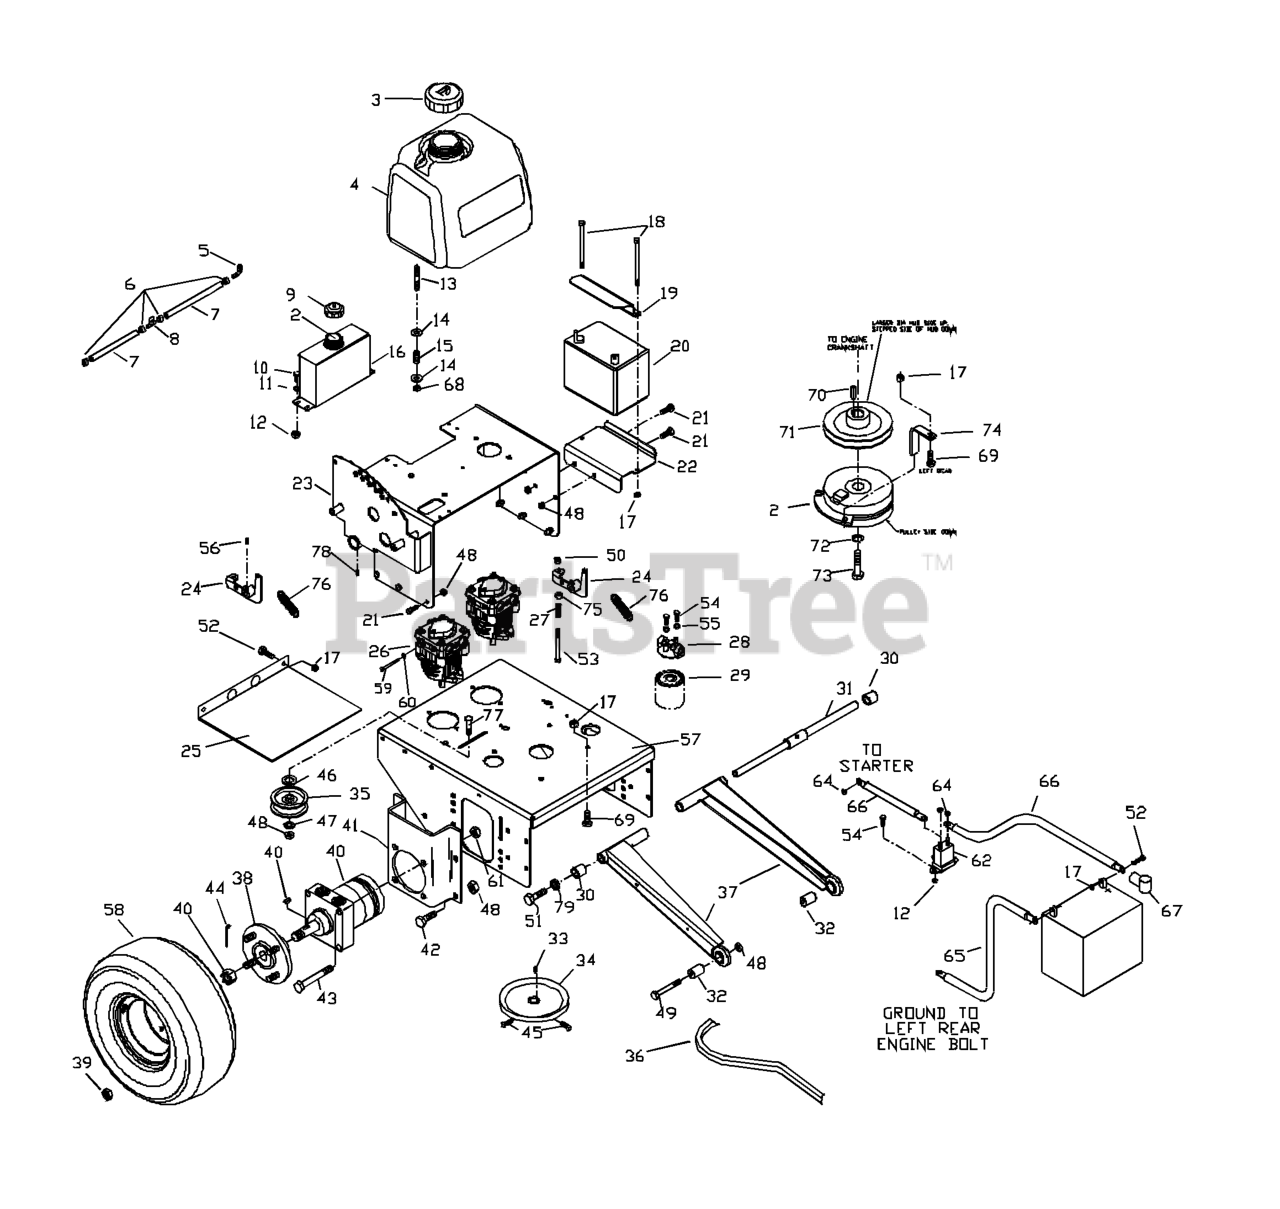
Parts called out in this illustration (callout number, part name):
1	CABLE, THROTTLE (17 KAW.)
3	FUEL CAP ANTI-SPLASH
5	HOSE BARB 90 DEGREE
6	HOSE CLAMP
7	GAS LINE 10"
8	FUEL VALVE
9	HYDRAULIC CAP
10	HCS 1/4C X 3/4 HCS
11	WASHER 1/4 FLAT
12	NUT 1/4C CENTER LOCK
13	STUD, 5/16C
14	WASHER 5/16 FLAT
16	OIL TANK BLK
17	NUT 5/16C CENTERLOCK
18	HEX SCREW 5/16 X 7.5
19	BATTERY STRAP
20	BATTERY WET NOT SELLABLE
21	SCREW 3/8C X 3/4 HEX CAP
22	BATTERY TRAY
23	TANK SUPPORT
24	PUMP ARM WELDMENT
25	LOWER BELT SHIELD
26	PUMP
28	FILTER HEAD
29	HYDRAULIC OIL FILTER
31	STRUT SHAFT
32	FRONT SPACER
33	KEY 5 MM SQ X 25 MM
35	IDLER PULLEY
36	TRANSMISSION BELT
37	STRUT WELDMENT
38	HUB.WHEEL.ZTR
39	LUG NUT 1/2F
40	WHEEL MOTOR
41	MOTOR MOUNT
42	HCS 3/8-16X1.GRD.5.ZD
43	HCS 1/2C X 2 3/4
44	COTTER PIN
45	SCREW 5/16C X 5/8 SQ HEAD
46	WASHER 1/2 FLAT
47	WASHER 3/8 FLAT
48	NUT 3/8C CENTERBLOCK
49	HCS 3/8C X 2 1/4
50	NUT 3/8-16 NYLOC
51	HHCS 1/2-13 X 1
52	HCS 5/16C X 3/4
53	HEX SCREW 3/8-20 X 2.75
54	HCS 1/4C X 5/8
55	LOCKWASHER 1/4"
56	5/16C X 5/8 "V" POINT
58	TIRE/WHEEL ASSY
58	TIRE.TURF.SAVER.18X7.5-8
58	VALVE STEM TR-412
58	WHEEL
59	CLEVIS PIN
60	NUT PUSH
61	NUT 1/2-13 HEX NYLOC ZD
64	NUT.1/4-20.HEX.NYLOC.ZD
65	CABLE-NEGATIVE
66	CABLE POSITIVE, LONG
68	NUT 5/16 NYLOC
69	HCS 5/16C X 1 3/4
70	KEY 1/4 SQ X 1 1/8
72	WASHER 7/16 LOCK
73	BOLT 7/16F X 2 1/2
74	CLUTCH TIE DOWN
76	SPRING-TRANS
77	RHSNB 3/8C X 2
78	ZERK
79	WASHER 1/2" SPLIT LOCK
